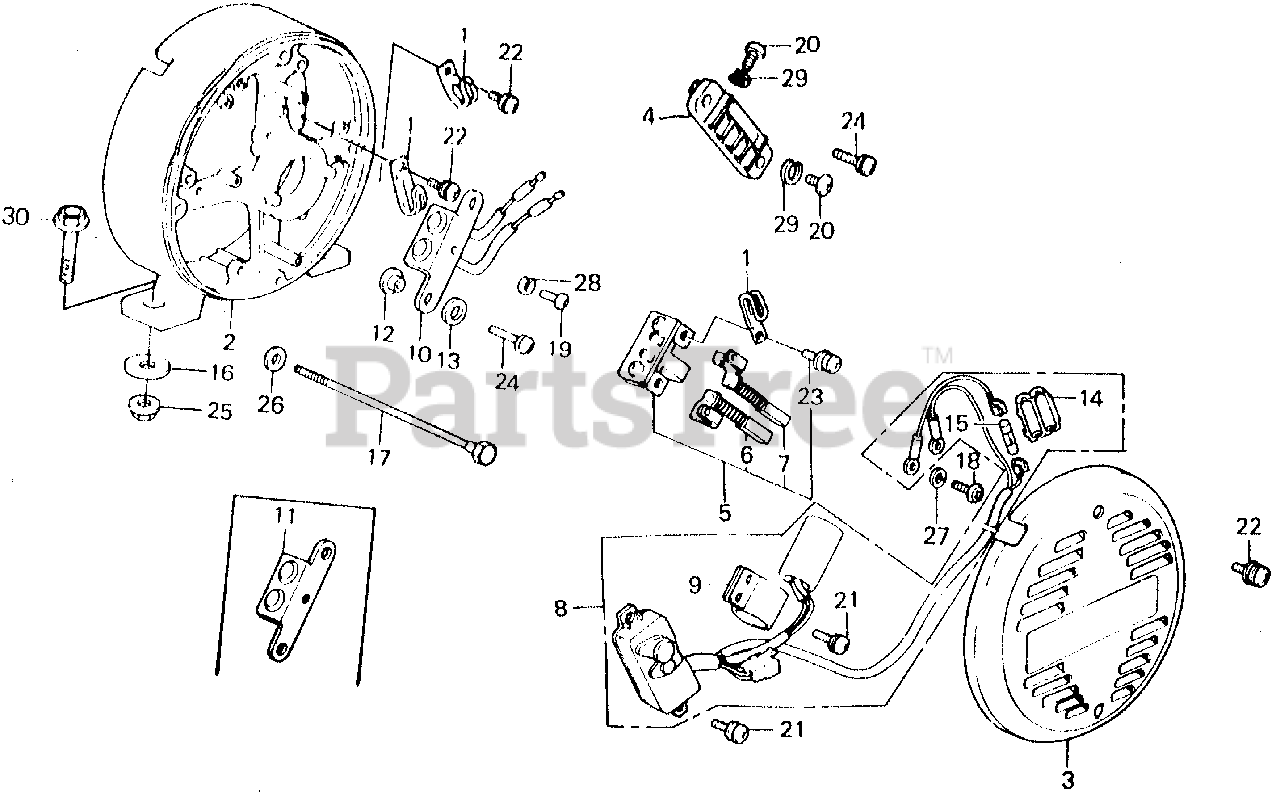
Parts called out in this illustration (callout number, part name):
1	CLAMP B, WIRE
2	HOUSING, RR. *NH31* (MCKINLEY WHITE)
3	COVER, GENERATOR *R8* (BRIGHT RED)
3	COVER, ALTERNATOR END *R8* (BRIGHT RED) (NOT AVAILABLE)
4	TERMINAL, A.C. OUT
5	HOLDER ASSY., BRUSH
8	REGULATOR ASSY., AUTOMATIC VOLTAGE
8	REGULATOR ASSY., AUTOMATIC VOLTAGE (NOT AVAILABLE)
9	HOLDER, CONDENSER
10	DIODE ASSY., D.C.
11	DIODE, D.C. (NOT AVAILABLE)
12	BUSH, INSULATING
13	WASHER, INSULATING
14	CASE, FUSE CONNECTOR
15	FUSE ASSY., SPARE
16	WASHER, EX. MANIFOLD
17	BOLT, HEX. (6X190) (SOURCE: VINTAGE PARTS INC.)
18	SCREW, PAN (4X8)
19	SCREW, PAN (5X12)
20	SCREW, PAN (6X8)
21	SCREW-WASHER (5X12)
22	SCREW-WASHER (5X10)
23	SCREW-WASHER (5X14)
24	SCREW-WASHER (5X20)
25	NUT, FLANGE (10MM)
26	WASHER, PLAIN (6MM)
27	WASHER, SPRING (4MM)
28	WASHER, SPRING (5MM)
29	WASHER, SPRING (6MM)
30	BOLT, FLANGE (10X32)
